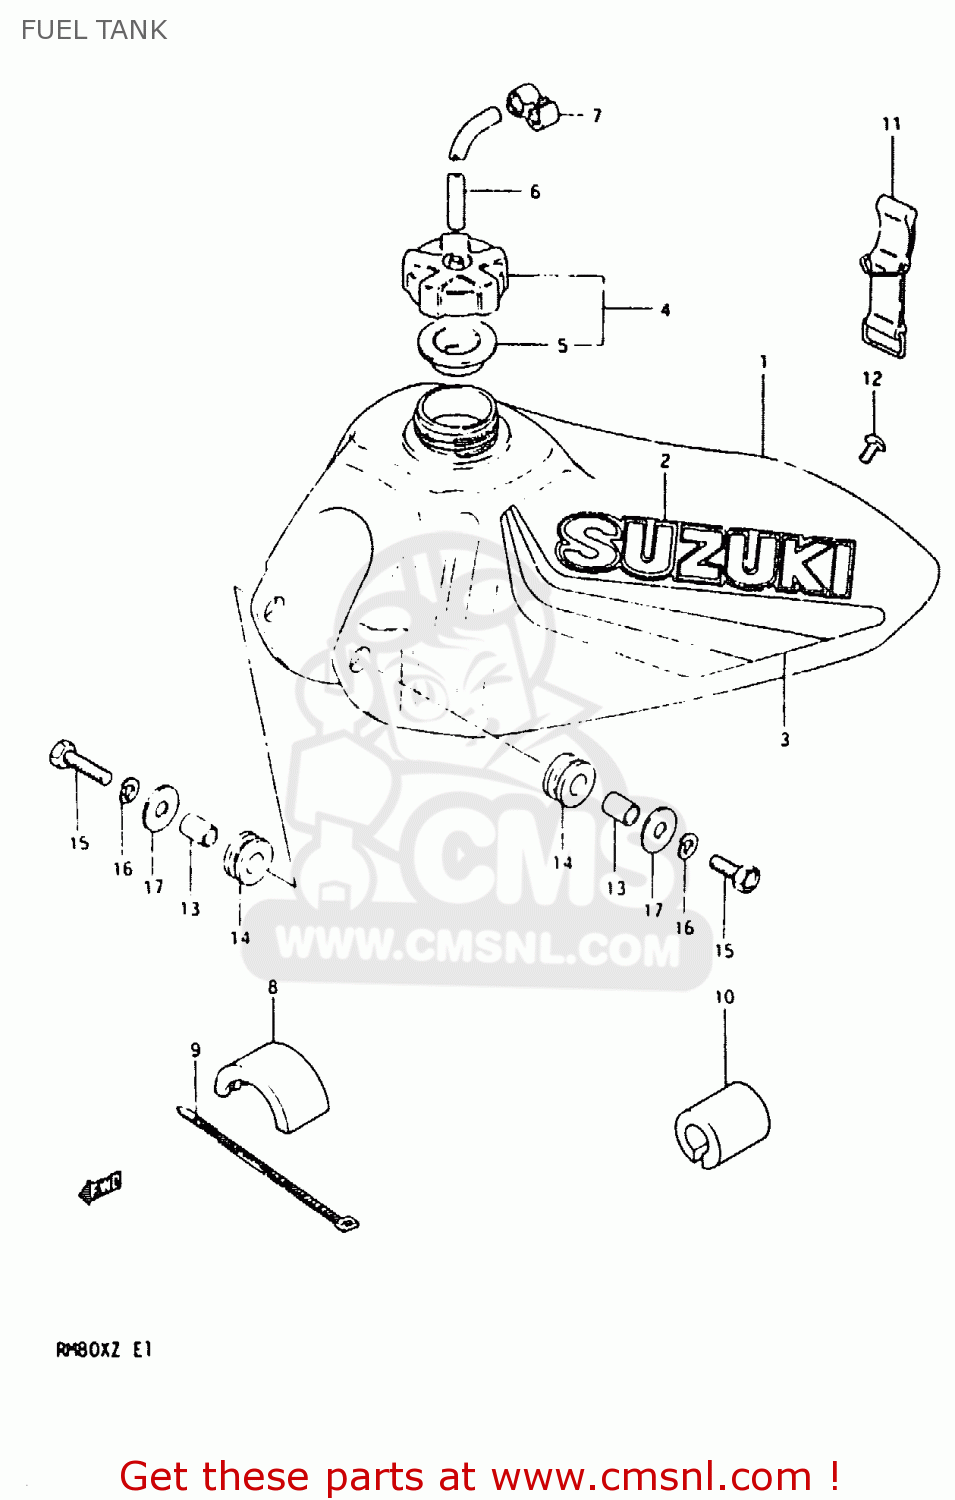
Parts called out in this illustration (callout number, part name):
1	TANK ASSEMBLY,FUEL
2	EMBLEM
3	TAPE SET,FUEL TANK
4	CAP,FUEL TANK FILLER
5	GASKET,FUEL TANK CAP (NAS)
6	HOSE
7	CLAMP,FUEL TANK BREATHER HOSE
8	CUSHION,FUEL TANK UPR FR
9	CLAMP
10	CUSHION,FUEL TANK UPR RR
11	BAND
12	SCREW (6X15)
13	SPACER (6.8X10X11.5)
14	CUSHION
15	BOLT
16	LOCK WASHER
17	WASHER(6.5X18X1)
